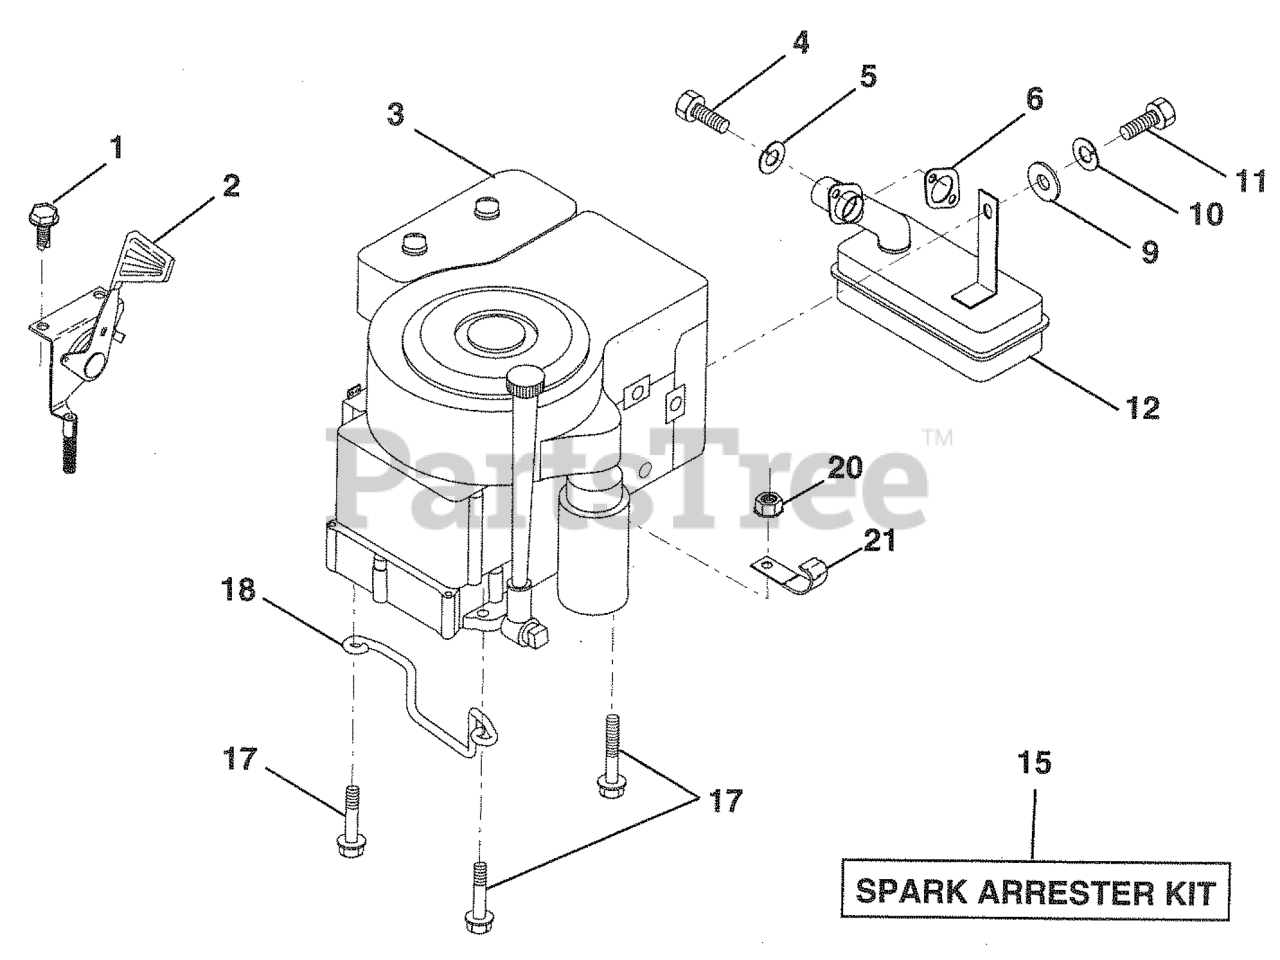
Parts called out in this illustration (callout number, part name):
2	CONTROL.TH/CH.RH.BLK.FLG.26
4	SCREW
5	WASHER.LOCK.HVY.HLCL.SPR.5/16
6	GASKET ENGINE
9	WASHER
10	LOCKWASHER
11	Bolt
12	MUFFLER.SINGLE.B&S.12HP
15	KIT.SPARK ARRESTOR 794945 B&S
17	SCREW LT
18	KEEPER,DR BELT GR
21	CLIP T
